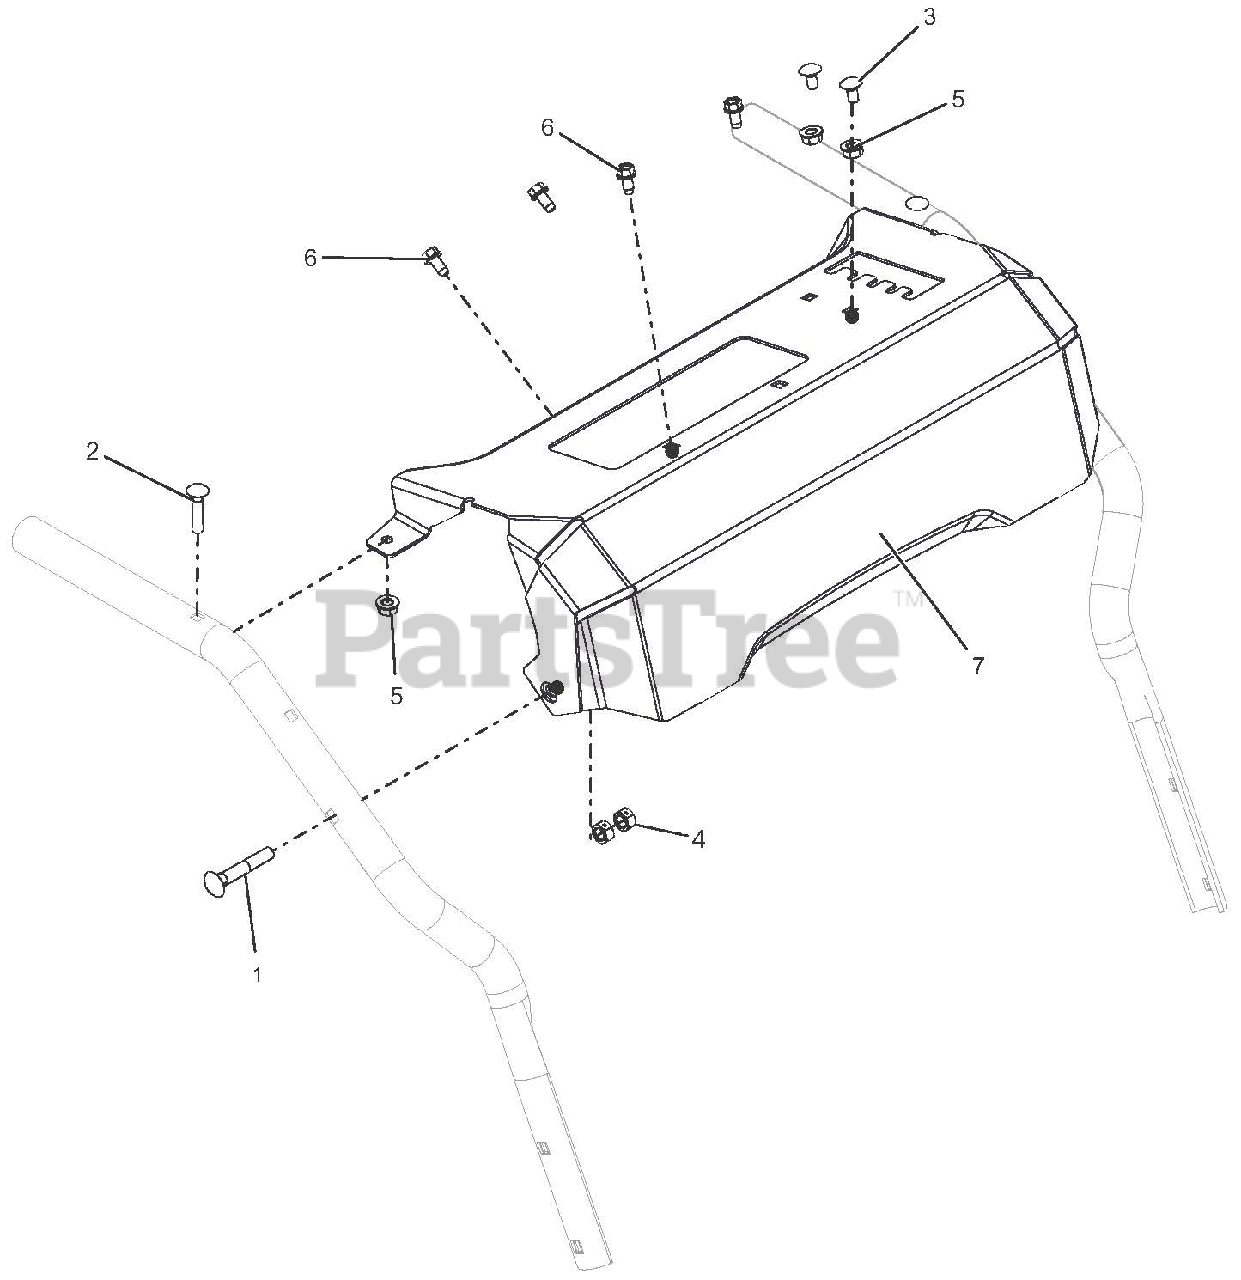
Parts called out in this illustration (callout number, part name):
1	BLT-RDHDXLSQNK .31-18X2.0 G5YZ
2	BLT-RDHDXLSQNK.25-20X1.25 G5ZC
3	@BLT-RDHDSQNK .25-20X.50 G5YZ
4	@NUT-LK-CTR .31-18 YWZC
5	@NUT-LK-TOP-FLG .25-20 YWZC
6	SCR-TAP .25-20X.50 HWH TR YWZ
7	CTRL PANEL W/DECAL,SNO-TEK,REM
